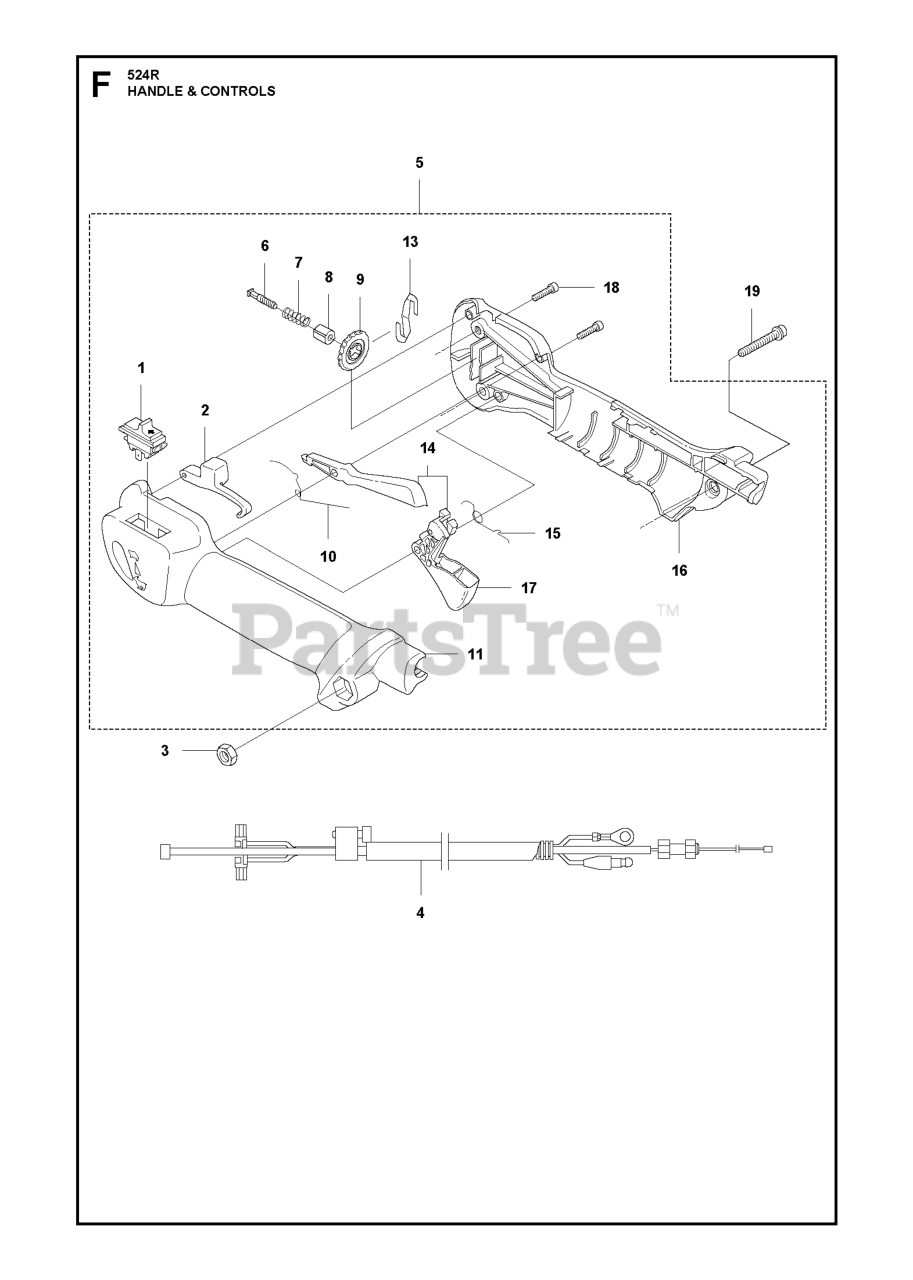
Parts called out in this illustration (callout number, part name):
1	START/STOP SWITCH
2	LOCKOUT STARTER THROTTLE
4	CABLE ASSY
6	SCREW
7	SPRING
8	HUB
9	STEERING WHEEL
11	HANDLE HALF LEFT
12	HANDLE
13	PLATE
14	THROTTLE CONTROL
17	THROTTLE TRIGGER
18	SCREW
19	SCREW
